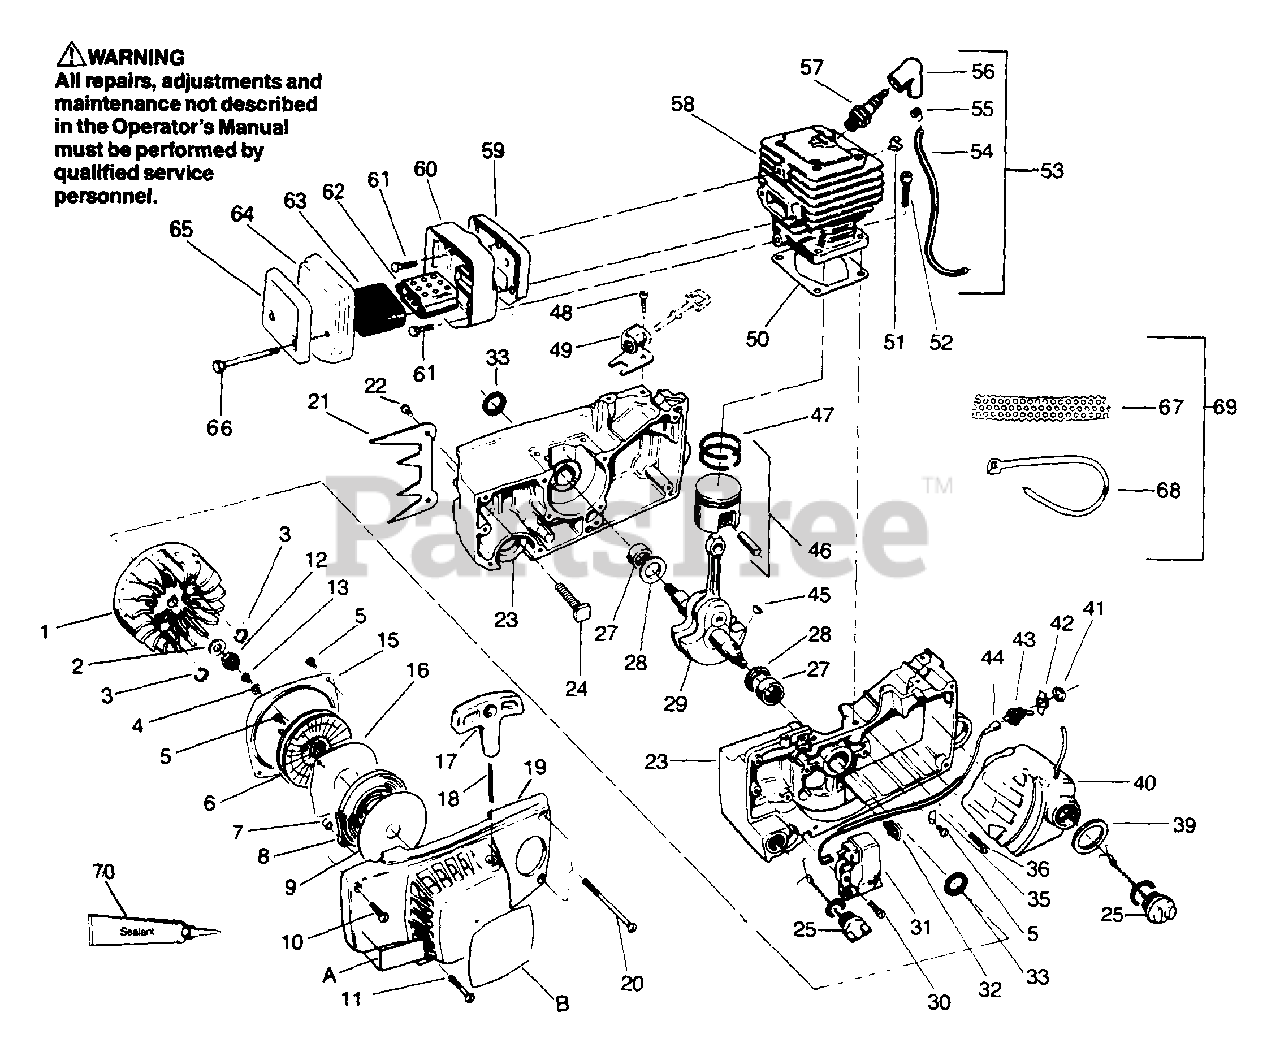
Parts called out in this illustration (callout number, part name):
1	Flywheel Ass'y.
2	Washer - Flywheel
3	Spring- Starter Dog
4	Washer - Starter Pulley
5	Screw - 32 x 5/16- Hex Hd.-Disc Mounting (also Air Baffle & Clamp Head)
6	Pulley - Starter
7	Bushing Recoil Spring
8	Spring Starter Recoil
9	Disc. Recoil Spring - Outer
10	Screw - 10-24 x 1 Oval Hd. Fan Housing - (Top Front)
11	Screw - 10-24 x 1-3/8 Fan Housing (Lower Front)
12	Flywheel Nut - 3/8-24
13	Screw - 10-24 x 1/8 - Starter pulley
15	Air Baffle
16	Disc Recoil Spring - Inner
17	Handle Starter Rope
18	Rope Starter (Bulk 9128)
19	Fan Housing Assembly
20	Screw - 10-24 x 3-9/64 - Fan Housing (Rear)
22	Screw - 10-24 x 9/16 - Hex Hd. - Spur
23	Crankcase Ass'y.
24	Kit-Bar Stud Replmnt. (5/16")
25	Oil & Fuel Cap Kit
27	Bearing - Crankshaft
28	Thrust Washer- Crankshaft
29	Crankshaft Assy.
30	Screw - 10-24 x 7/8 - Module Mnt.
31	Ignition Module
32	Clamp - High Tension Lead - Crankcase
33	Seal - Crankshaft
35	Clamp- Module Lead
36	Screw - 10-24 x 11/16 - Fit. Hd. Crankcase
39	Seal- Fuel Tank Neck
40	Fuel Tank Ass'y.
41	Nut - Switch Mounting
42	Plate - Ignition Switch
43	Switch - Toggle
44	Leadwire - Switch
44	Serial #35474496
44	Before Serial #35474495
45	Key - Flywheel
46	Piston Assembly
47	Rings - Piston
48	Screw - 10-24 x 3/8-Fil. Hd. Choke Bracket
49	Bracket & Bushing Assembly - Choke
50	Cylinder Gasket
51	Clip - High Tension Lead Cylinder
52	Cylinder Screw- 1/4-20 x 1/8
53	High Tension Lead Assembly
54	High Tension Lead
55	Connector - Spark Plug
56	Boot- Spark Plug
57	Spark Plug
58	Cylinder
59	Back Plate - Muffler
60	Muffler Body
61	Screw - 1/4-24 x 1/2 - Hex Hd Muffler Body to Cylinder
62	Diffuser - Muffler
63	Screen - Spark Arrestor
64	Muffler Cover
65	Shield Muffler
66	Screw - 1/4-20 x 2-1/2 - Hex Cap Muffler Cover
67	Screen - Winter
68	Tie Strap
69	Winter Kit
70	Sealant - Crankcase
A	Decal - Professional User
B	Decal- Fan Housing
